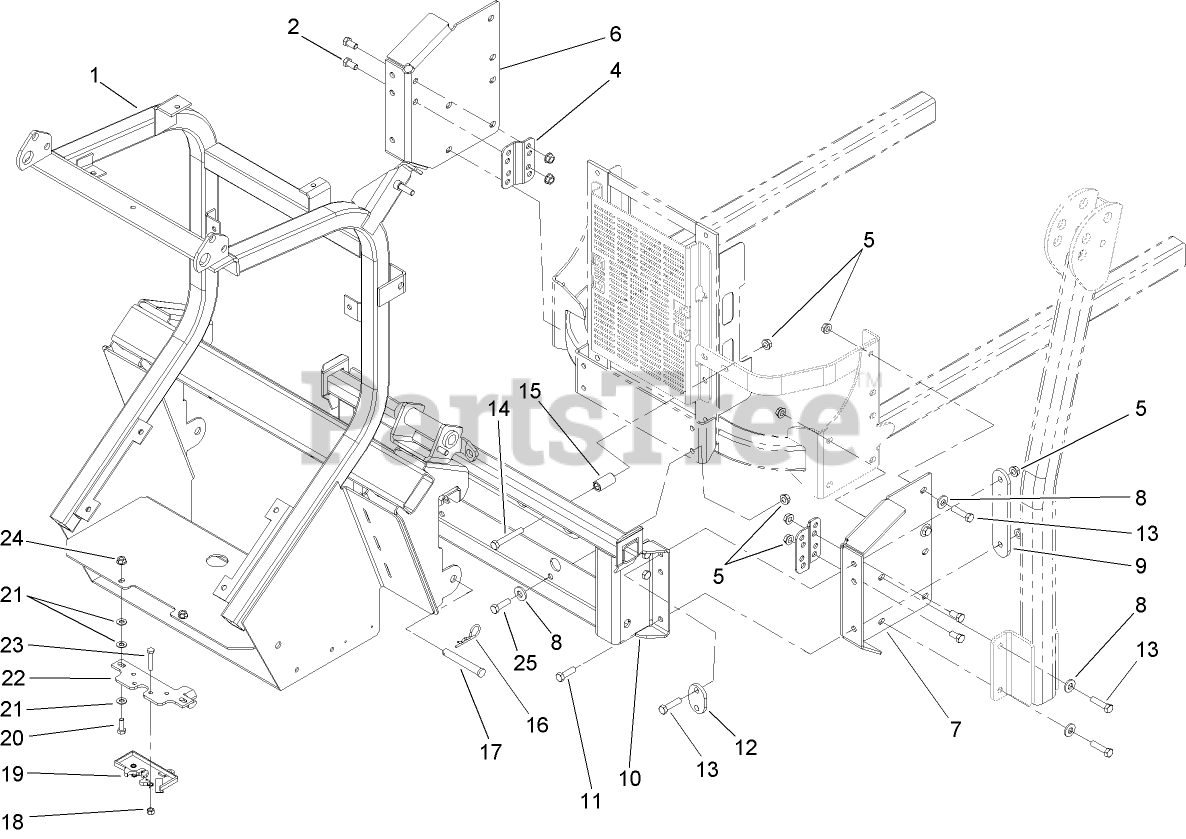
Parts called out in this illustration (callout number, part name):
1	HOPPER FRAME ASM
2	SCREW-HH
4	BRACKET-STIFFENER
5	NUT-HHF, WHIZ
6	BRACKET-MOUNT, BAGGER, LH
7	BRACKET-MOUNT, BAGGER, RH
8	WASHER-BELLEVILLE
9	SPACER-FRAME
10	BAGGER MOUNT ASM
11	SCREW-HH
12	SPACER-FRAME, SHORT
13	SCREW-HH
14	SCREW-HH
15	SPACER
16	PIN-COTTER
17	PIN-CLEVIS
18	NUT-LOCK, NI
19	LATCH-ROTOR
20	SCREW-HH
21	WASHER-PLAIN
22	BRACKET-LATCH
23	SCREW-HH
24	NUT-HF
25	SCREW-HH
